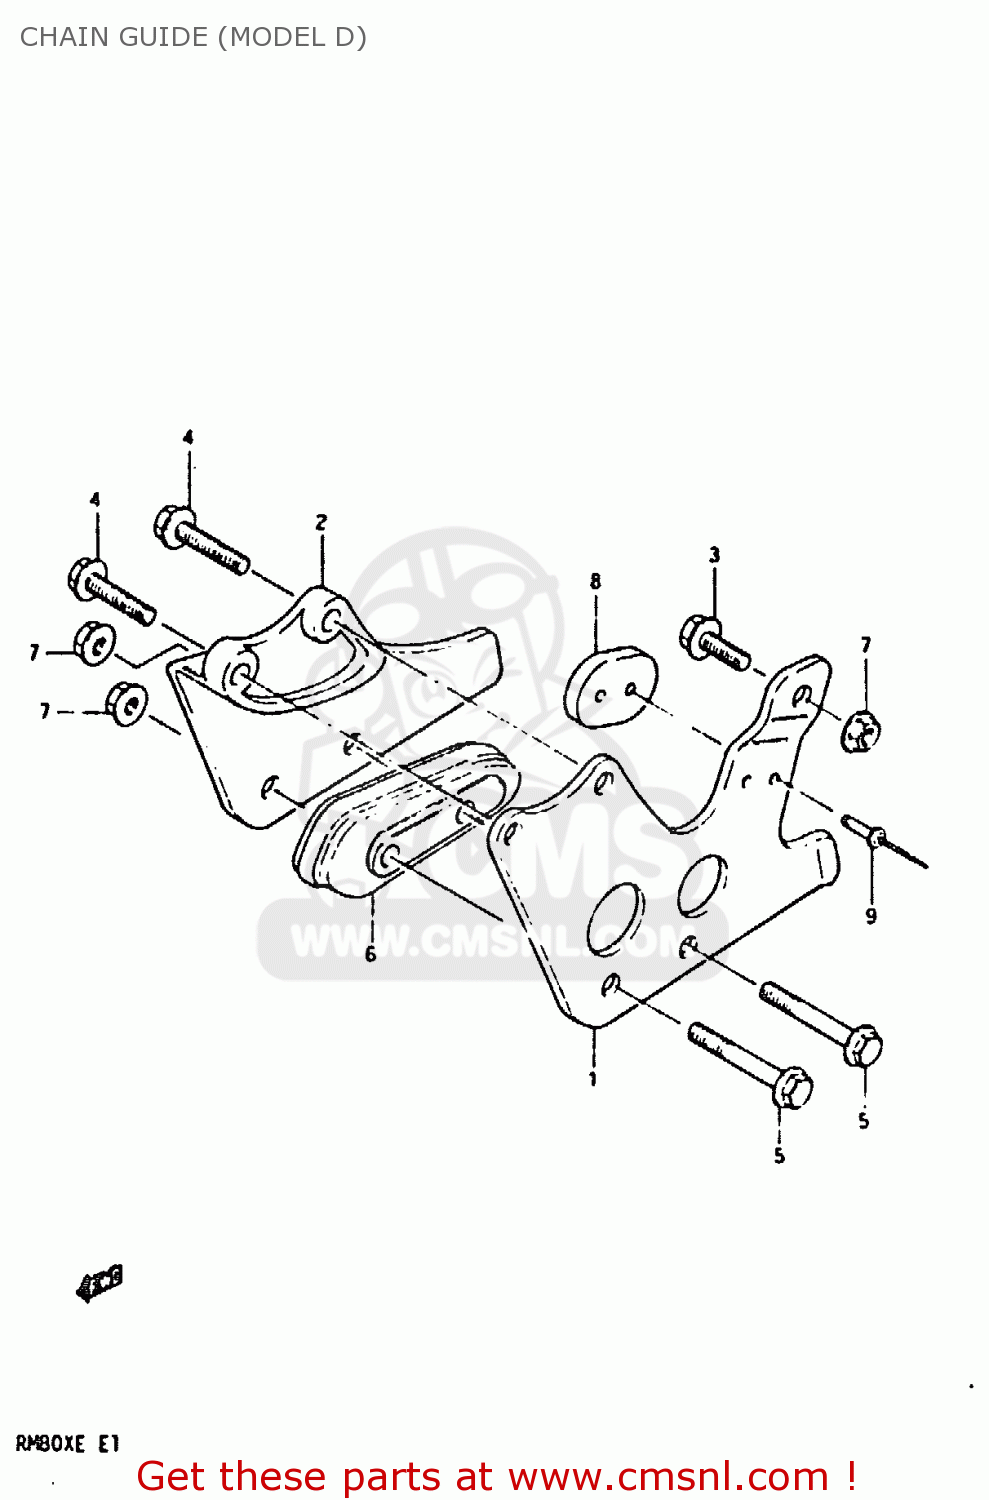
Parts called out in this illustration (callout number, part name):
1	GUIDE,CHAIN
2	PLATE,CHAIN GUIDE INNER
3	BOLT
4	BOLT
5	BOLT
6	DEFENSE,CHAIN GUIDE
7	NUT
8	PAD,DRIVE CHAIN GUIDE
9	RIVET
